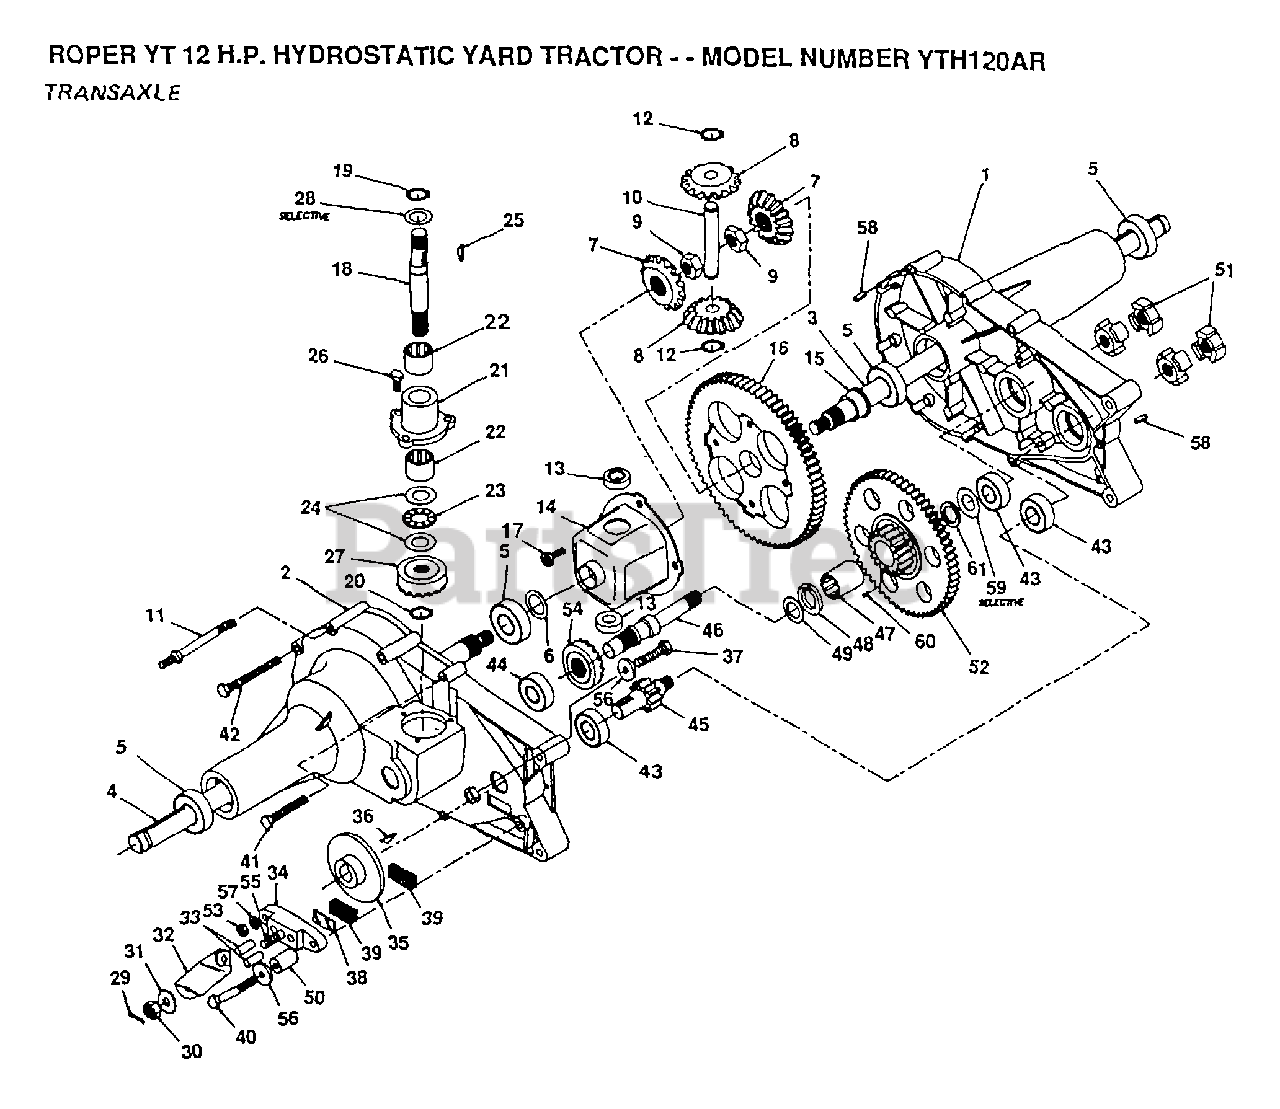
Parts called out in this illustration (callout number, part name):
1	HSG HALF LH-44077
2	HSG HALF RH-44076
3	AXLE LH -44273
4	AXLE RH-44272
5	BEARING.44121.AGR
6	WASHER -44008
7	GEAR MITER -44096
8	GEAR MITER -44097
9	NUT -44133
10	SHAFT CROSS
11	SCREW-STUD -44271
12	SNAP RING -44146
13	"THRUST, BEARING -44128"
14	HOUSING.ASM.DIFF.-62590
15	"FLANGE, BEARING-44129"
16	GEAR
17	BOLT -44126
18	SHAFT INPUT-44270
19	SNAP RING -44145
20	RET RING (44144)
22	"NEEDLE, BEARING 44099"
23	BEARING.NEE.44139
24	WASHER-44109
25	KEY.44136.HYDRO
26	SCREW
28	WASHER -44125
29	PIN COTTER -44101
30	NUT -44142
31	WASHER FLAT -44130
32	ARM BRAKE 23710
33	PIN BRAKE ACTUATO -44127
34	BRAKE YOKE
35	DISC BRAKE -(44090)
36	KEY -44143
37	SCREW -44277
38	PLATE PUCK -44134
40	SCREW -44300
41	SCREW -44123
42	SCREW -44124
43	"BALL, BEARING -44147"
44	"BALL, BEARING -44232"
45	SHAFT PINION 44083
46	SHAFT DRIVE-44080
47	NEEDLE BEARING -44342
48	THRUST.BRONZE -44343
49	WASHER-44151
50	SPACER -23711
53	NUT -43178
54	PINION-DR.44079
55	BOLT SQ HD
56	WASHER -44278
57	WASHER -44137
58	PIN ROLL-44269
60	DOWEL PIN -44346
61	SEAL GREASE -44394
